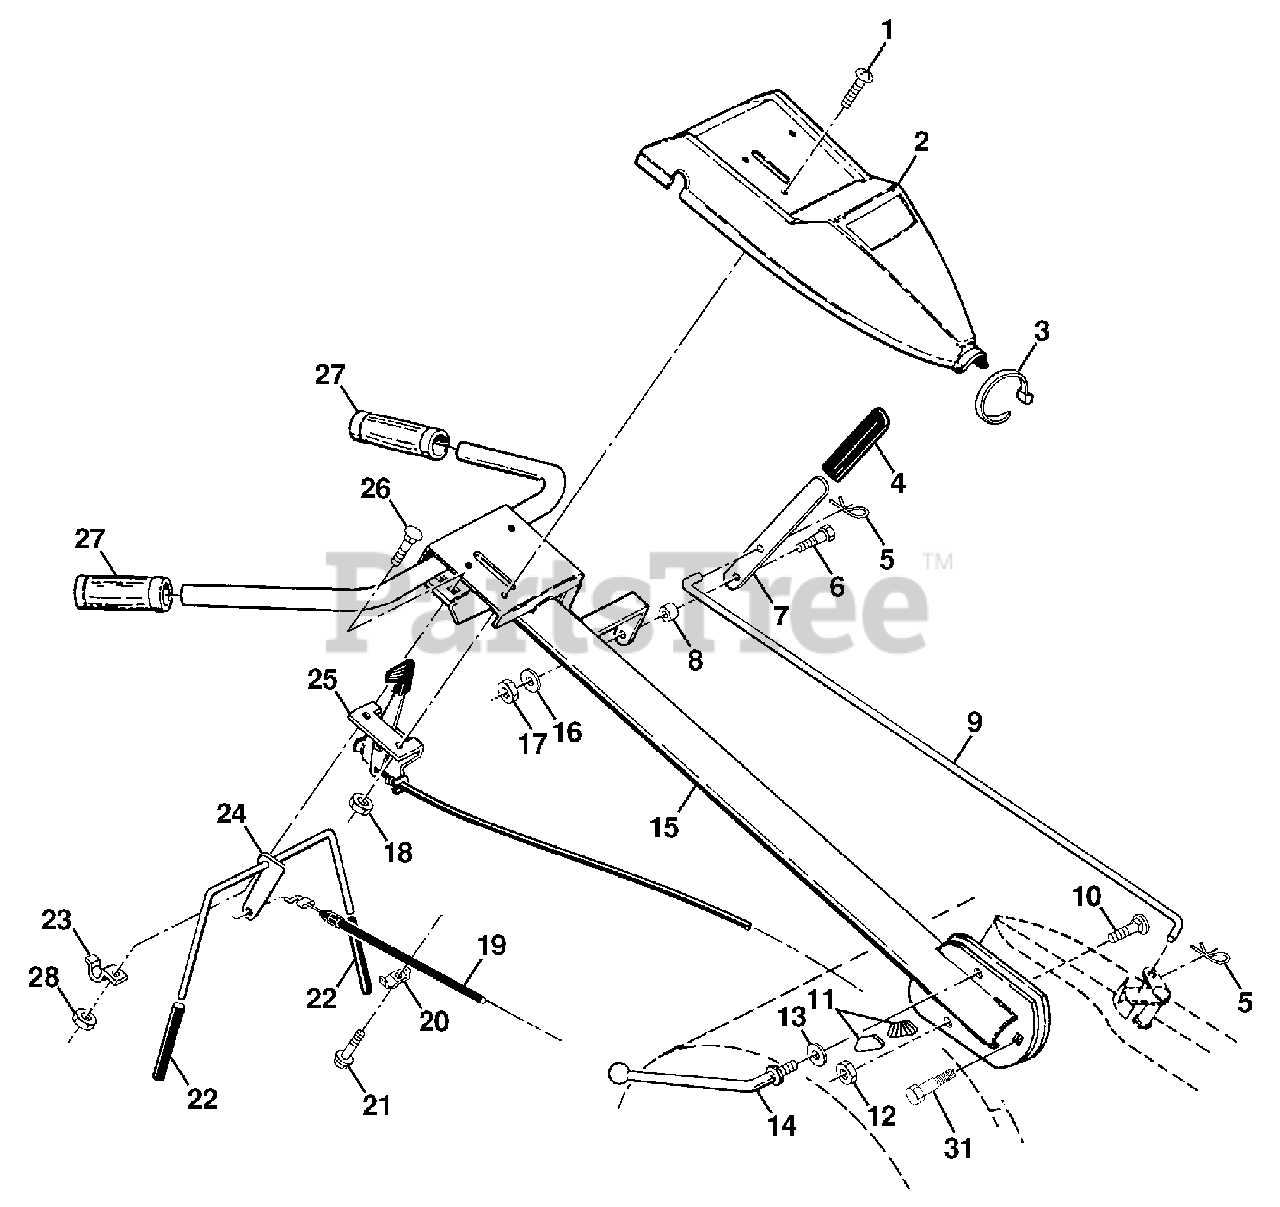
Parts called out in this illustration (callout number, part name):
1	Screw, PHD. #10-24
2	Panel, Control
3	Tie, Cable
4	Grip, Handle
5	Clip, Hairpin
6	Bolt, Shoulder
7	Handle, Shift
8	Grommet, Rubber
9	Rod, Shift
10	Bolt, Carriage 3/8-16 x 1 Gr. 5
11	Lock, Handle
12	Nut, Centerlock 3/8-16
13	Washer 13/32 x 1 x 11 Ga.
14	Lever, Lock, Handle
15	Handle
16	Washer, Lock 1/4
17	Nut, Hex 1/4-20
18	Nut, Keps #10-24 UNC
19	Cable, Clutch
21	Screw, Hex Washer Hd. Slotted #10-24 x 1/2
22	Grip, Bar, Control
23	Clamp, Bar, Control
24	Bar Assembly, Control
25	Control, Throttle
26	Bolt, Carriage 1/4-20 UNC x 1/2
27	Grip, Handle
28	Nut, Keps Hex 1/4-20
31	Bolt, Pivot
